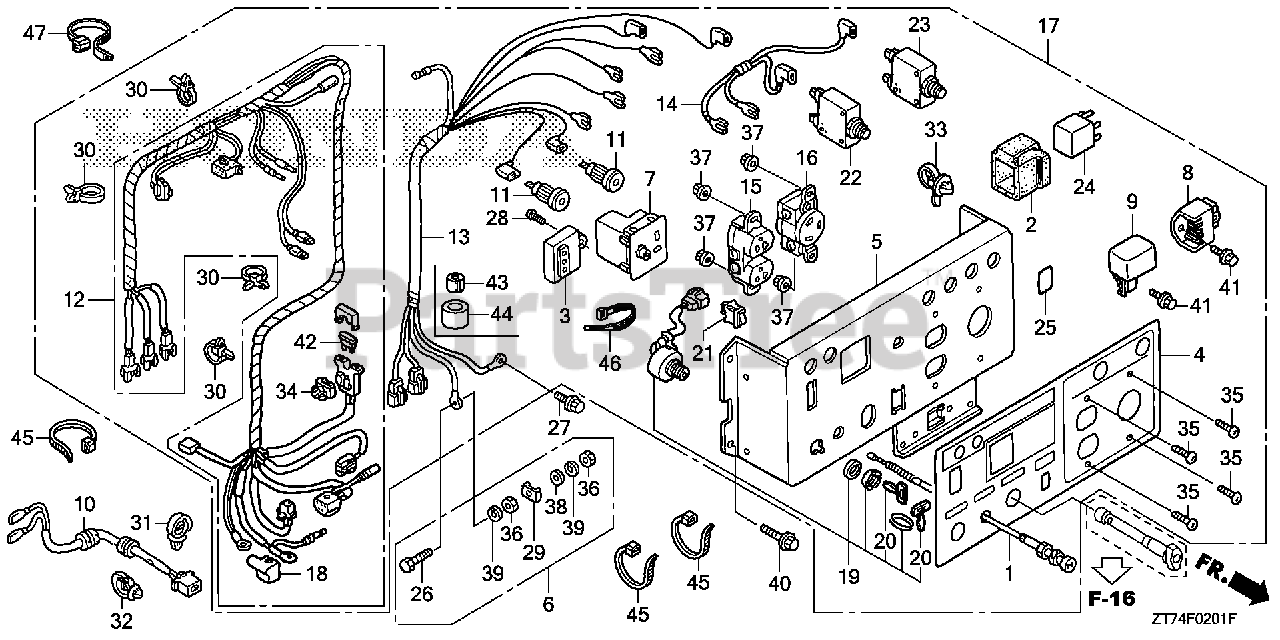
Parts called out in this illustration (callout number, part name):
1	CABLE, CHOKE
2	CUSHION, IGNITION CONTROL MODULE (CDI) (NOT AVAILABLE)
3	IGNITION UNIT
4	MARK, CONTROL PANEL
5	PANEL, CONTROL
6	TERMINAL SET, GROUND
7	RECEPTACLE, D.C.
8	RECTIFIER ASSY.
9	RECTIFIER, REGULATOR (NOT AVAILABLE)
10	WIRE HARNESS ASSY., ENGINE
11	SOCKET, COMPOSITE
12	WIRE HARNESS ASSY., CONTROL
13	WIRE HARNESS ASSY., MAIN
14	SUB-WIRE ASSY.
15	RECEPTACLE (20A/125V)
16	RECEPTACLE (30A/125V)
18	COVER, BATTERY TERMINAL (NOT AVAILABLE)
19	SWITCH ASSY., COMBINATION
20	KEY
21	SWITCH, AUTO-THROTTLE
22	PROTECTOR, CIRCUIT (20A)
23	PROTECTOR, CIRCUIT (30A)
24	RELAY ASSY., POWER (5P)
25	MARK, FUSE
26	BOLT, HEX. (6X28)
27	BOLT, FLANGE (6X12) (CT200)
28	SCREW, PAN (5X13)
29	RETAINER (6MM)
30	TIE, CABLE (NATURAL 225X5.0)
31	CLIP, WIRE HARNESS (25MM)
32	CLIP, HARNESS
33	CLIP, WIRE HARNESS (GRAY)
34	CLIP, CONNECTOR HOLDER (BROWN)
35	SCREW, PAN (4X10)
36	NUT, HEX. (6MM)
37	NUT, FLANGE (4MM)
38	WASHER, PLAIN (6MM)
39	WASHER, SPRING (6MM)
40	BOLT, FLANGE (6X10)
41	BOLT, FLANGE (6X10)
42	FUSE, BLADE (5A)
43	FILTER, SUB NOISE (AC)
44	SUPPORTER, FILTER
45	BAND, WIRE (95MM)
46	TIE, CABLE (NATURAL 154X3.4)
47	BAND, WIRE HARNESS
